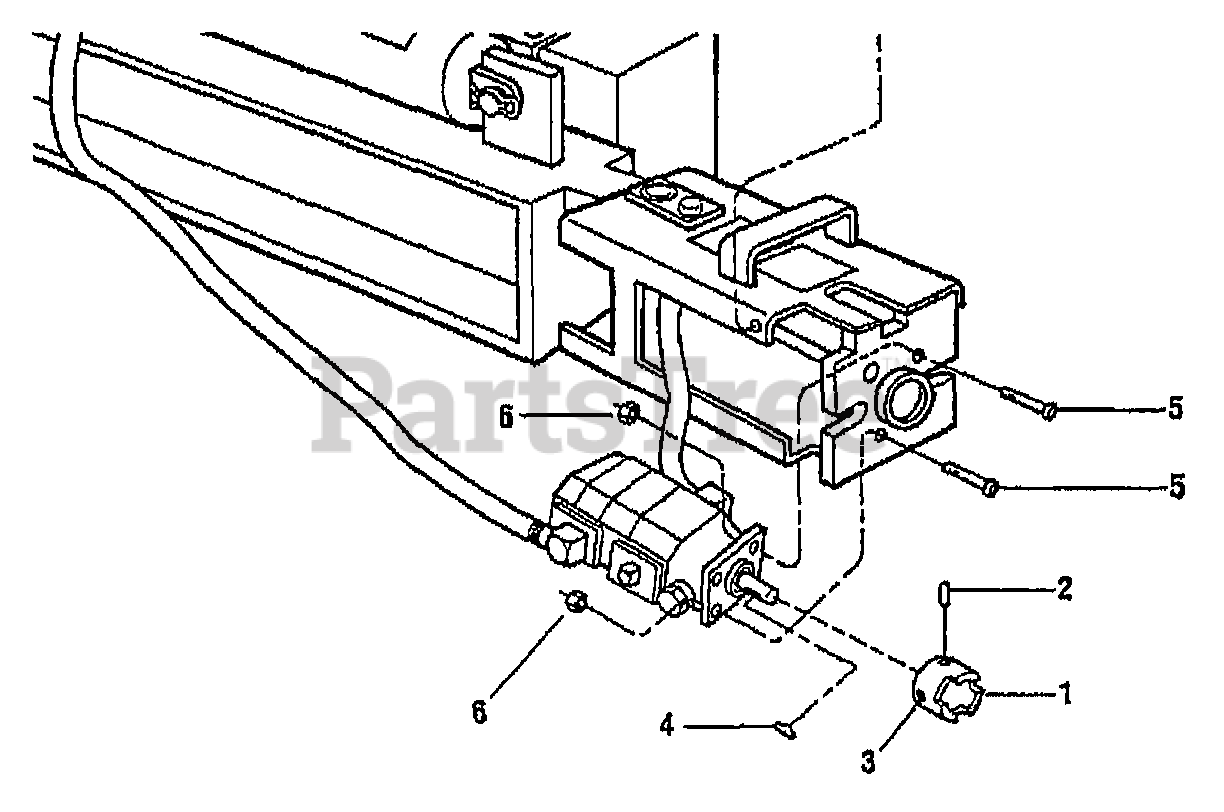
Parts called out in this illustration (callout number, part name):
1	CLUTCH-PTO96T-B
2	SCR-SET F/CLUTCH
3	PIN-SPIRAL F/CLUTCH
4	KEY-HI PRO F/CLUTCH
5	SCR-CAP 5/16"-18X1"
6	NUT-LOCK 5/16"-18
